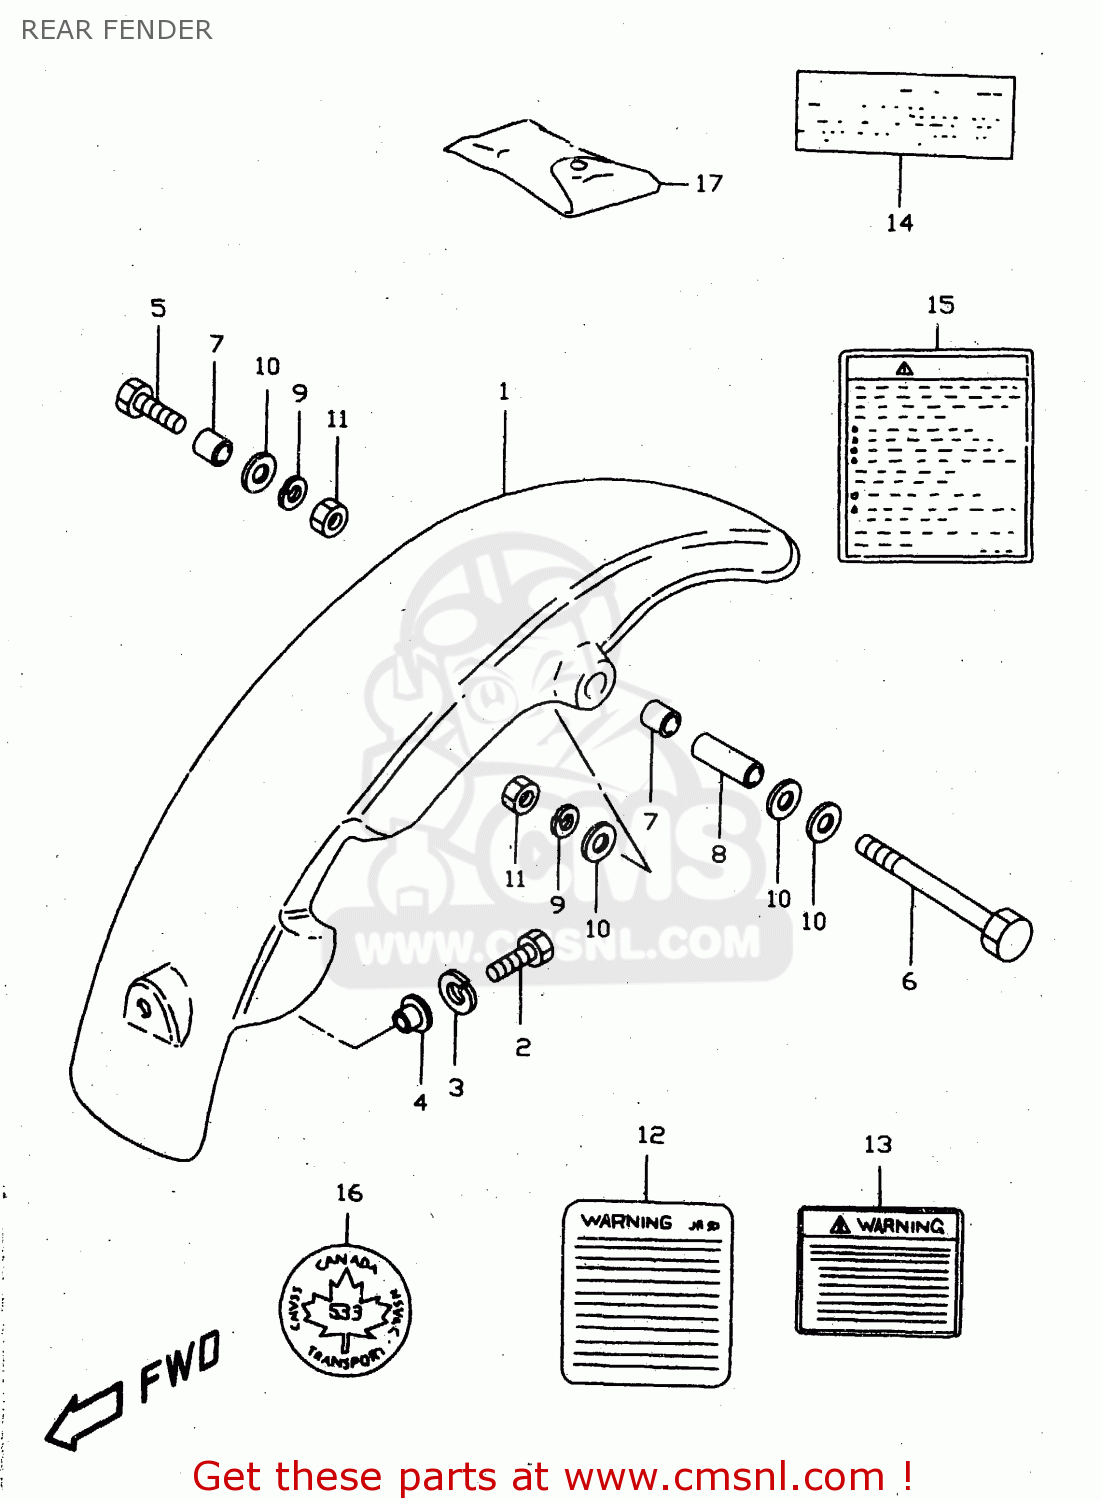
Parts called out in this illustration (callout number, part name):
1	FENDER,RR
2	BOLT
3	LOCK WASHER
4	WASHER
5	BOLT
6	BOLT, LH
7	SPACER,RR FENDER RR
8	SPACER (8.2X12.5X23.5)
9	LOCK WASHER
10	WASHER
11	NUT
12	LABEL,WARNING
13	LABEL,WARNING SAFETY
14	LABEL (MANUAL NOTICE)
15	LABEL, ATTENTION
16	PLATE
17	TOOL ASSY
18	MANUAL, OWNER'S
